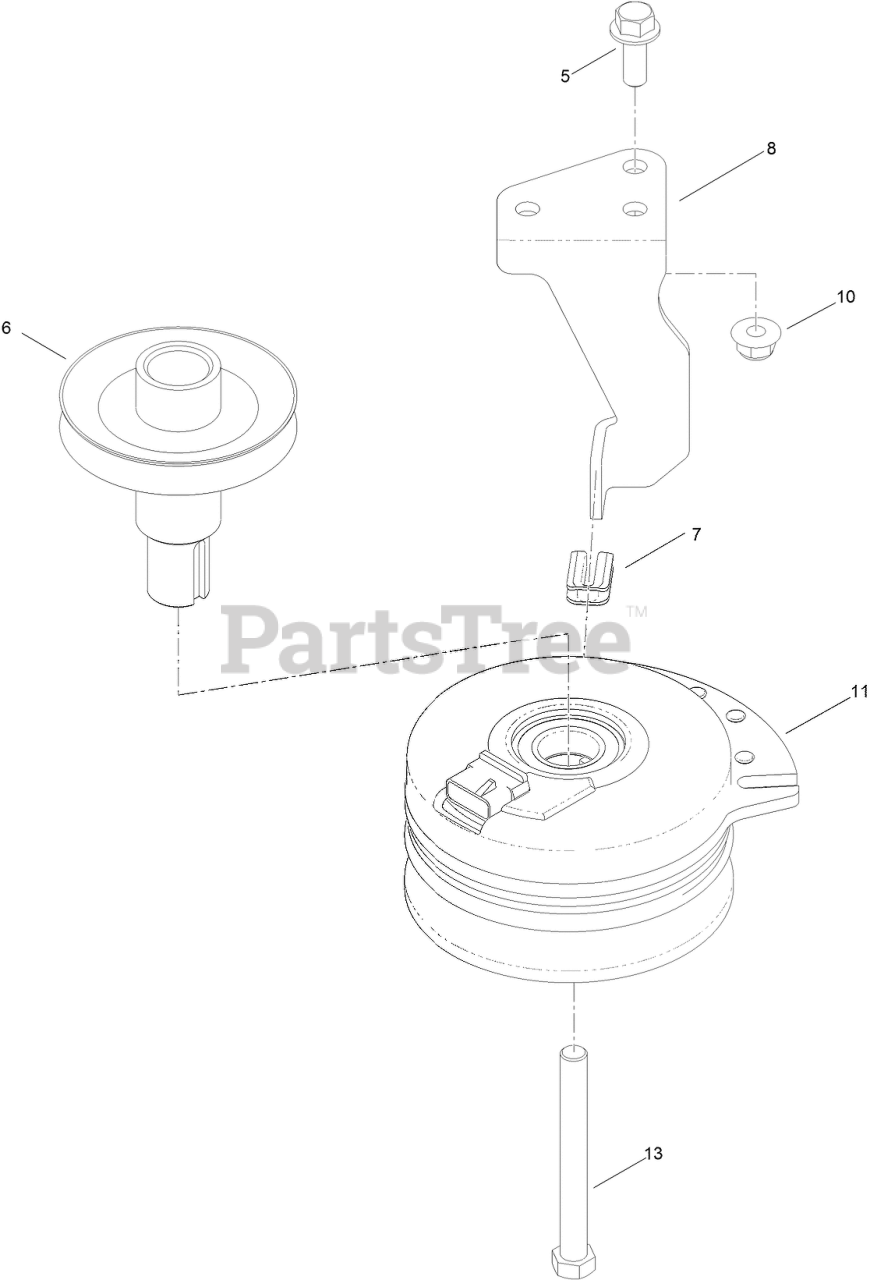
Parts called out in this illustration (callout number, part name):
5	SCREW-HHF
6	PULLEY-ENGINE
7	ISOLATOR-CLUTCH
8	STOP-CLUTCH
10	NUT-HF, NI
11	CLUTCH-ELECTRIC
13	SCREW-HH
